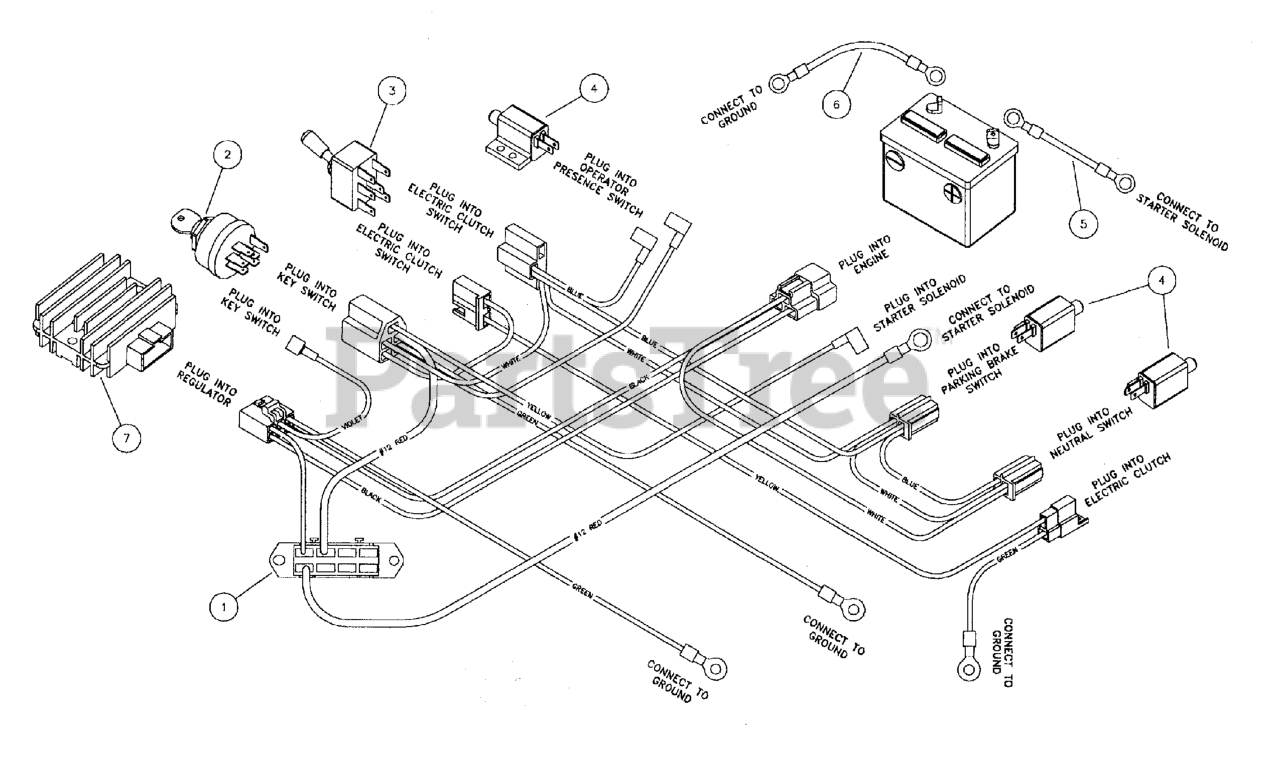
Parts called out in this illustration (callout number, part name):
2	SWITCH, IGNITION, 6 POST
3	SWITCH, Electric Clutch
4	SWITCH, PLUNGER, N.C.
5	POSITIVE (+) BATTERY CABLE, 30"
6	BATTERY CABLE, NEG, 22, 1/4-5/16
